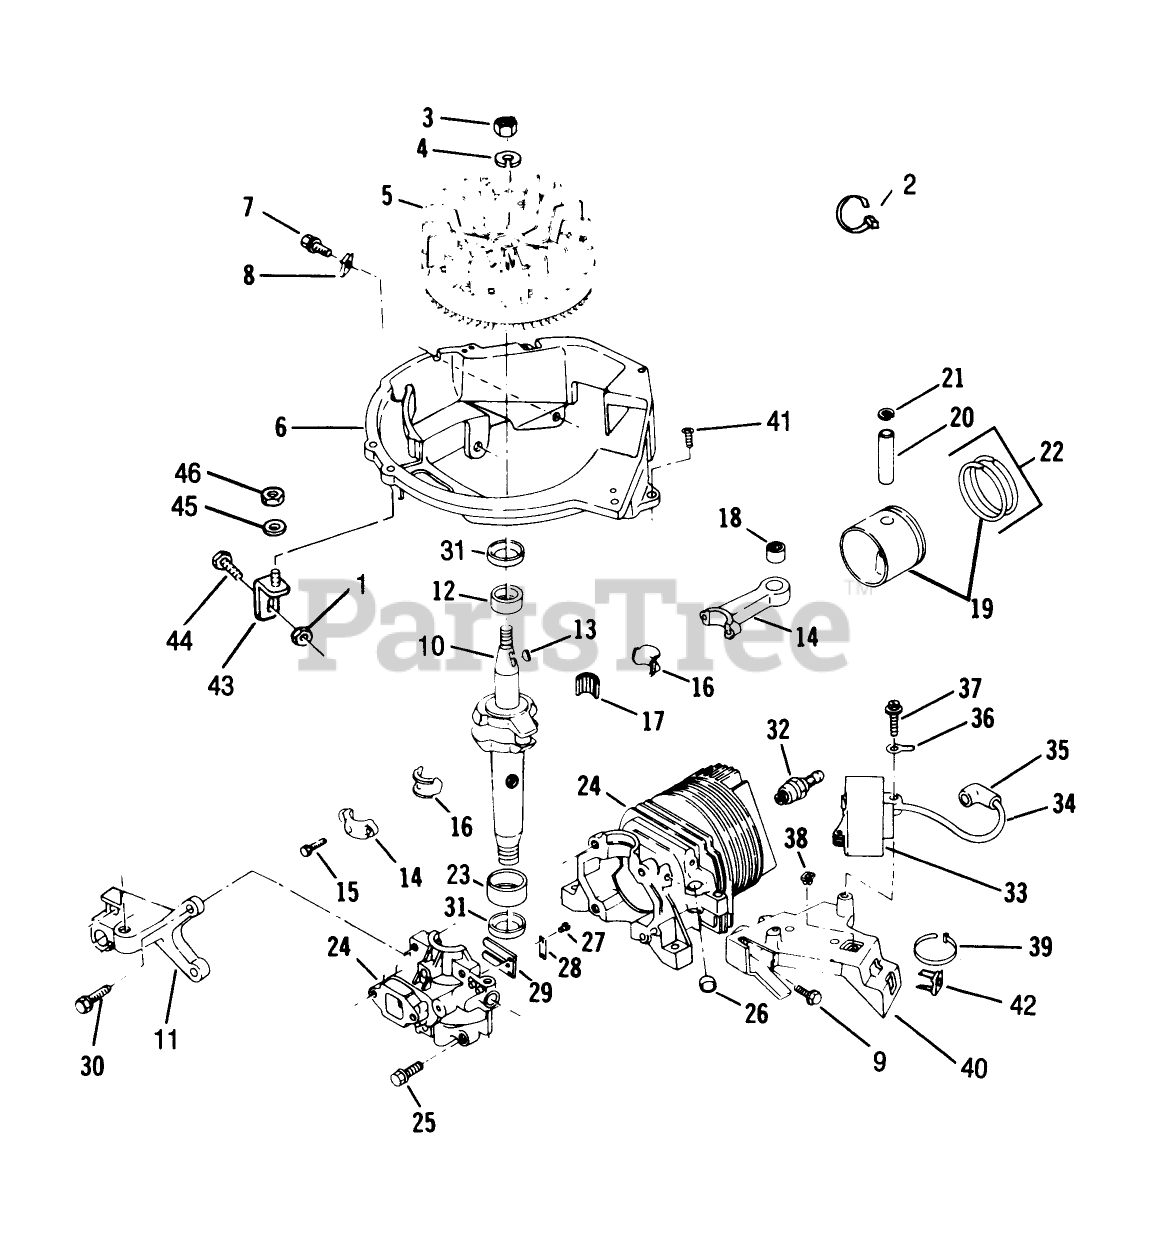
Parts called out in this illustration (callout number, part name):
1	NUT-LOCK F
3	NUT
5	FLYWHEEL ASSY F
7	SCREW-SEMS
11	BRACKET-BRAKE F
12	BEARING V
13	KEY
15	SCREW-HSH
16	LINER ASM
18	BEARING AY F
21	RING-RETAINING
23	BEARING V
25	SCREW S
26	PLUG-CORE VF
27	SCREW-HH
28	PLATE-BACKUP, REED
31	SEAL-OIL
34	HT LEAD&COVER XEV
36	TERMINAL S
38	NUT-CLIP
40	BRACKET S
41	SCREW F
42	NUT-CLIP
43	BRACE AY F
44	BOLT F
45	WASHER S
46	LOCKNUT E
